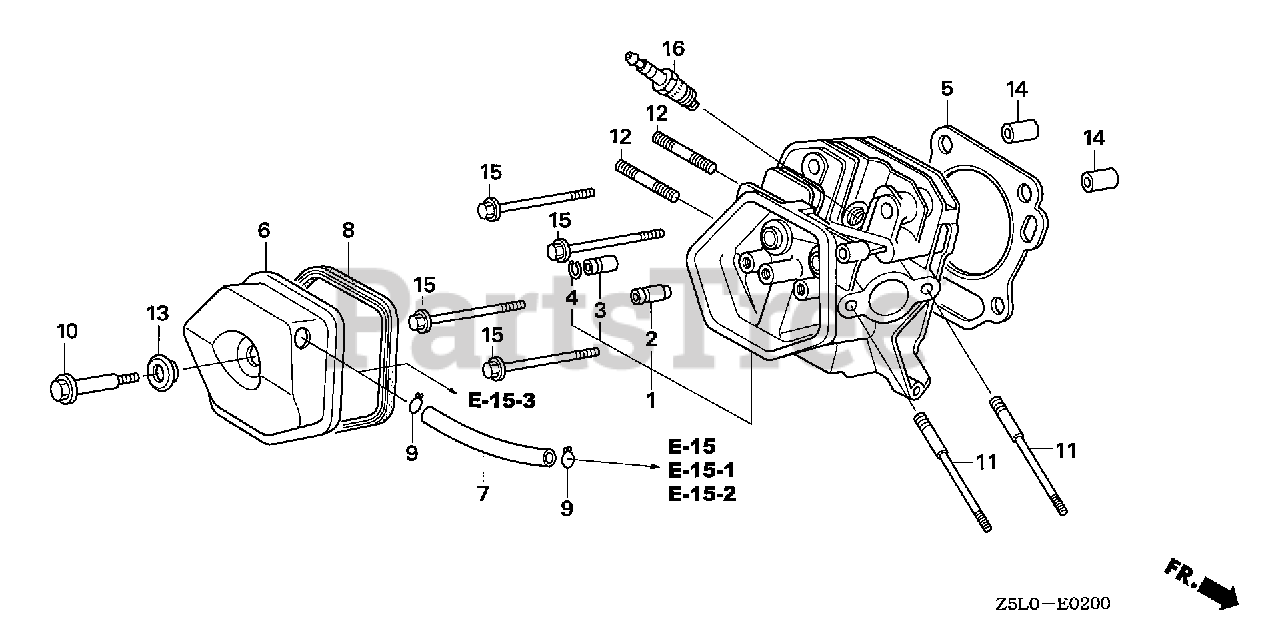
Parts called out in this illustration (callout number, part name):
1	CYLINDER HEAD
2	GUIDE, VALVE (OS)
3	GUIDE, EX. VALVE (OS)
4	CLIP, VALVE GUIDE
5	GASKET, CYLINDER HEAD (NIPPON LEAKLESS)
6	COVER, HEAD
6	COVER, CYLINDER HEAD
8	GASKET, CYLINDER HEAD COVER
10	BOLT, HEAD COVER
11	BOLT, STUD (8X106)
11	BOLT, STUD (8X115)
12	BOLT 2, STUD (8X32)
13	WASHER, HEAD COVER
14	PIN A, DOWEL (12X20)
15	BOLT, FLANGE (10X80)
16	SPARK PLUG (BPR5ES) (NGK)
16	SPARK PLUG (W16EPR-U) (DENSO)
